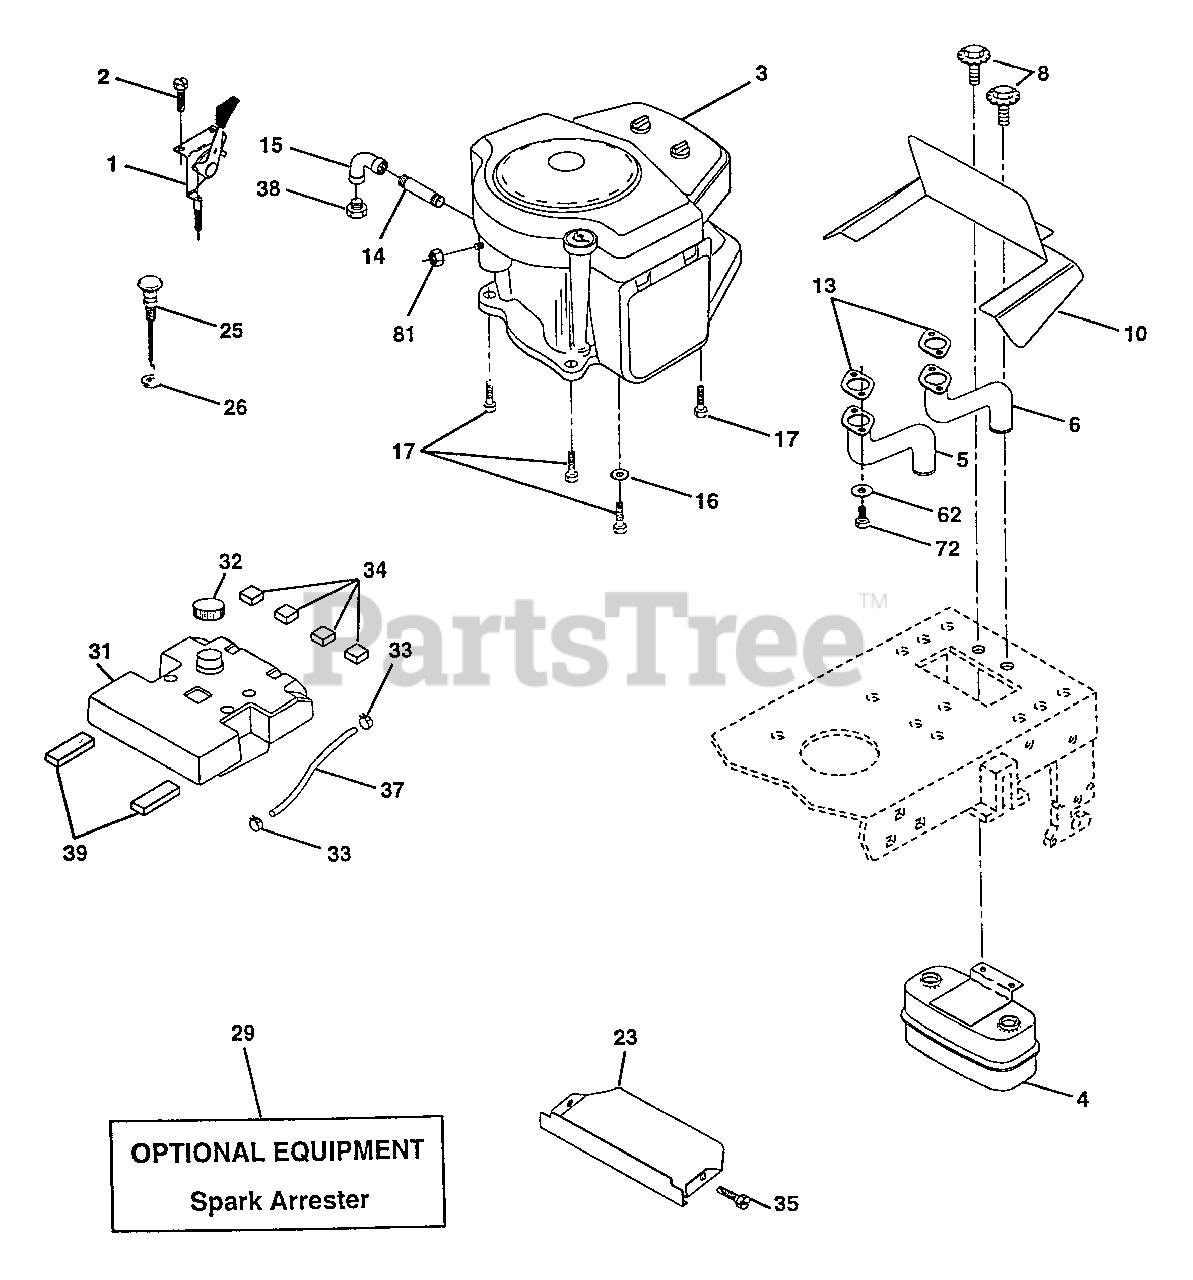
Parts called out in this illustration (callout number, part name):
1	Control Th/Flag 180 LH 36" (AYP part number)
2	Screw Hex Thd Cut 1/4-20x5/8 T
3	Engine, B&S Intek II
4	Muffler Asm Twin Lo-Tone
5	Pipe Exhaust LH Intek
6	Pipe Exhaust RH Intek
8	Bolt 5/16-18 UNC x 3/4 w/Sems
10	Shield Browning Intek II (AYP part number)
11	Washer Lock 5/16
12	Screw Hex Hd Cap 5/16-18 x 3/4
13	Muffler Gasket
14	Nipple Pipe 3/8 Npt X 4-1/2"
15	Elbow Std 90 Degree 3/8-18 Npt
16	Washer Lock Ext Tooth 3/8
17	Screw Thdrol 3/8-16 x 1-1/2
23	Shield Heat
25	Choke Control 37"
26	Nut, Keps 3/8-24 UNF
29	Kit Spark Arrestor (Flat Scrn)
31	Tank Fuel 3 50 STLT w/o Sensor
32	Cap Asm Fuel W/sym Vented
33	Clamp Hose Black
34	Pad, Spacer
35	Screw
37	Line Fuel
38	Plug Oil Drain
39	Pad, Idler
81	Nut Flange 1/4-20 Starter Nut
101	Nut, Flange M8-1.25 (AYP part number)
